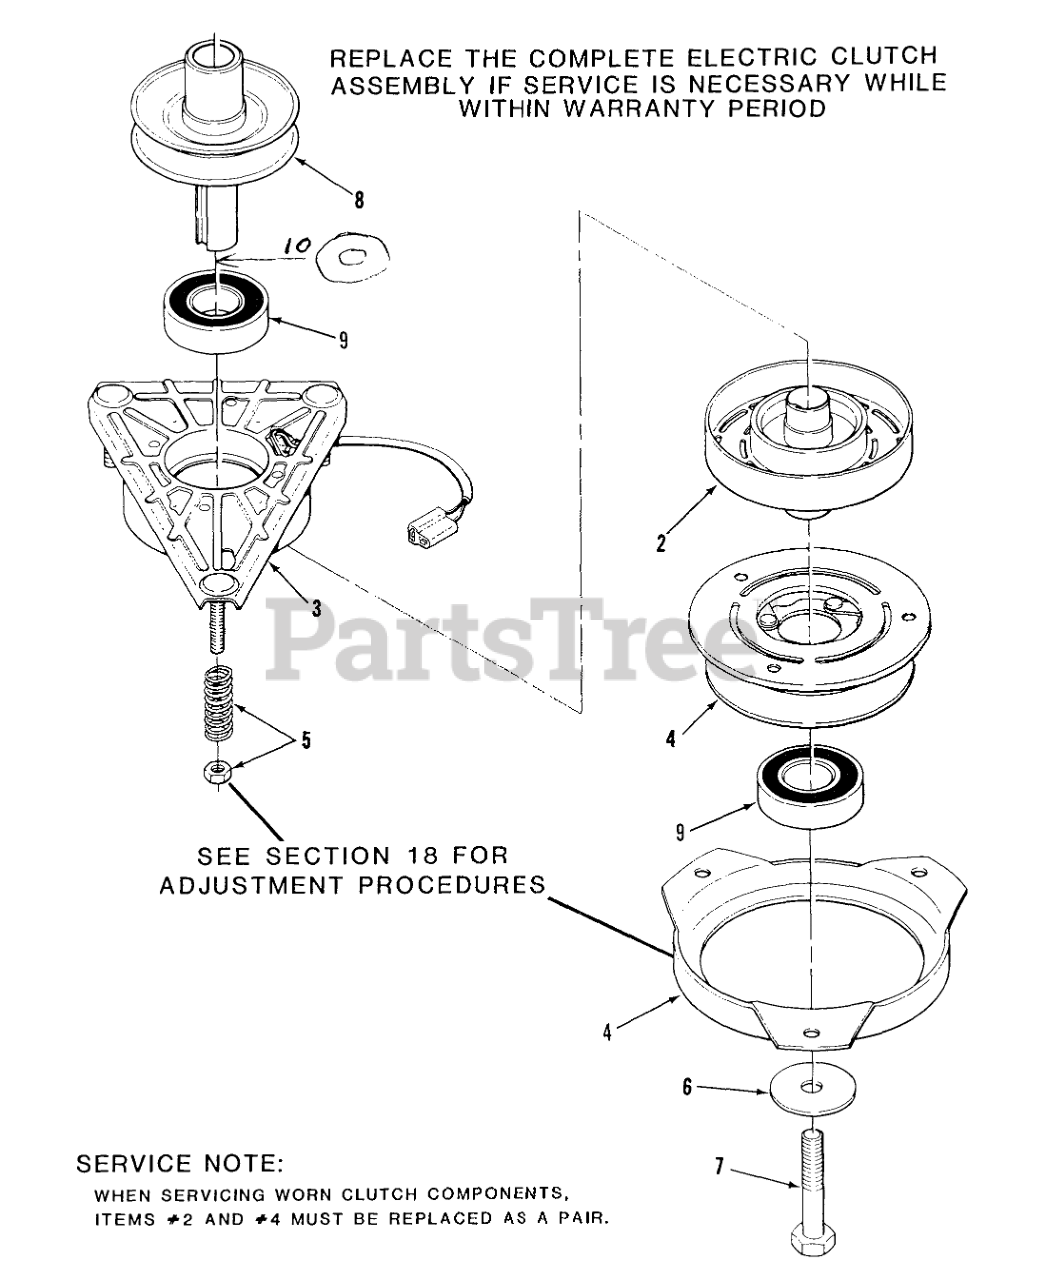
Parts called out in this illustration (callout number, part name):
2	ASS'Y-ROTOR
3	Field Assy (includes one of item 9)
4	Armature and Pulley Assy (includes one of item 9 and Brake Plate)
5	ACCESS SPRING & NUT
6	WASHER
7	HHCS M10X1.5X120
8	PULLEY-ENGINE
9	BEARING-ELEC CLUTCH
10	WASHER
